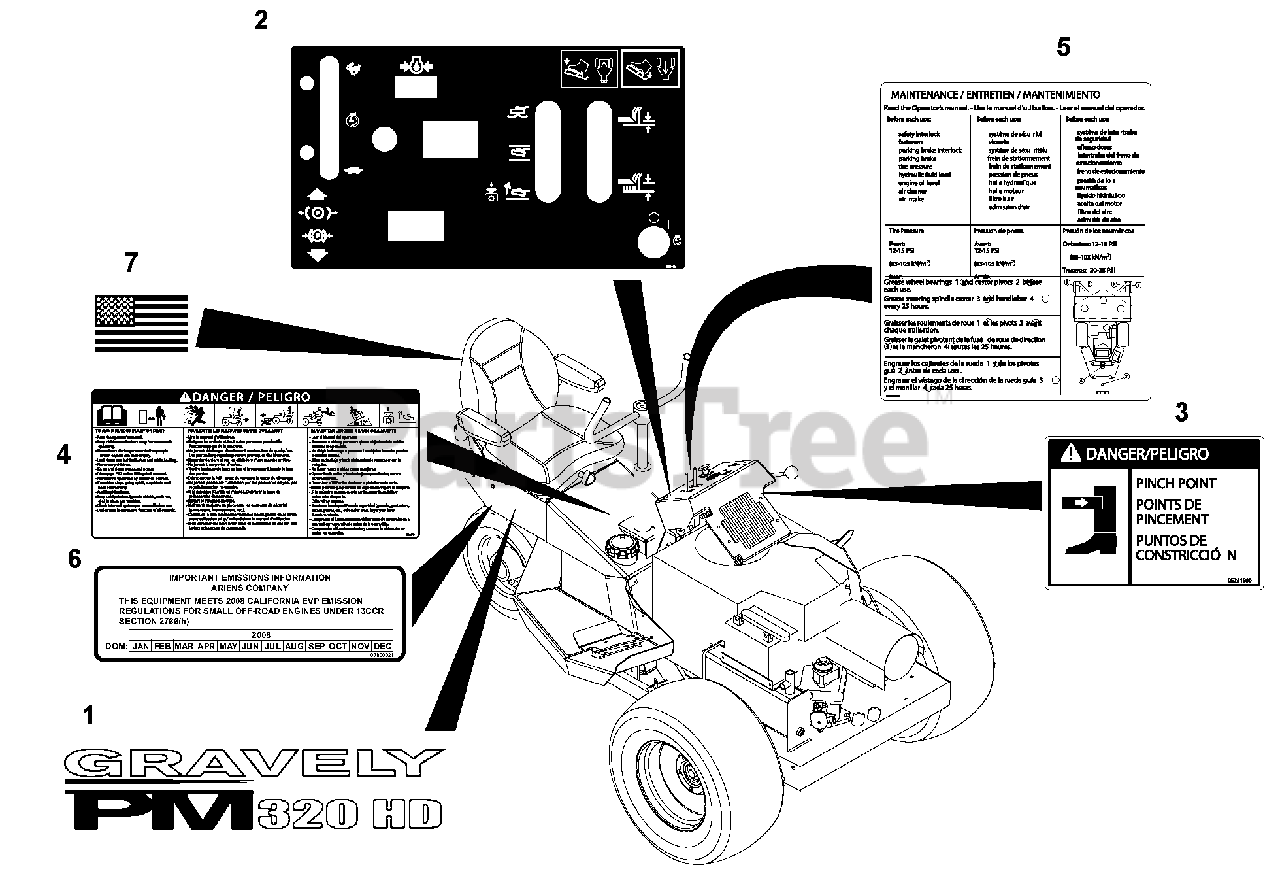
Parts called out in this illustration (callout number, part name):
1	Decal, PM-320
2	Decal, PM-310 Panel
3	Decal, Pinch Point
4	Decal, PM-310 Danger
5	Decal, PM-310 Maintenance
6	Decal, Carb Label
7	Decal, American Flag
